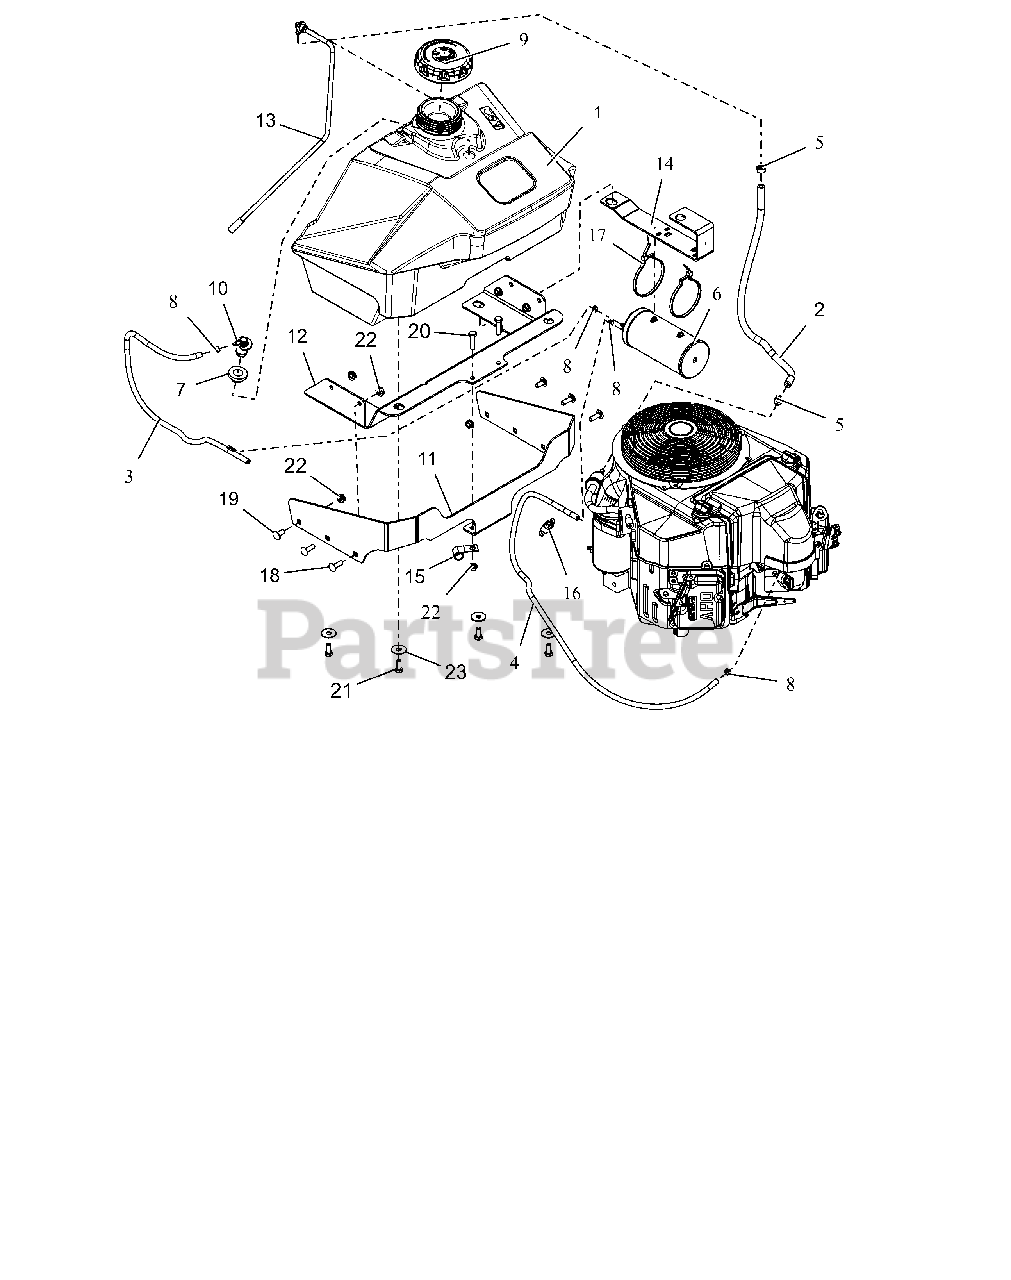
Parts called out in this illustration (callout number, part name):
1	TANK, PRO-WALK
2	HOSE, .25 LOW-PERM BULK GAS
3	HOSE, .188 LOW-PERM BULK GAS
4	HOSE, .188 LOW-PERM BULK GAS
5	CLAMP, FUEL LINE
6	400 CC CARBON CANISTER 3/16 PT
7	GROMMET, REMOTE VENT NITRILE
8	CLAMP-HOSE, SPRING .188
9	CAP, FUEL NONVENT AUTOLOCK
10	VALVE, 2-WAY
11	BRKT, FUEL TANK MTG (RED)
12	BRKT, FUEL
13	ASM, PROWALK FUEL TANK PICK UP
14	BRKT, CARBON CANISTER MTG (RED)
16	CLIP, T, .38-.50
17	CABLE TIE, .19 X 14.4
18	@BLT-RHDSSQNK .31-18X1.00 G5YZ
19	@BLT-RHDSSQNK .31-18X.75 G5YZ
20	@BLT-HEX .31-18X1.25 GR5 YWZC
21	@BLT-HEX .31-18X.75 GR5 YWZC
22	@NUT-LK-CTR-FLG .31-18 YZ GR F
23	WSHR-FL-STL .375X1.125X.065YWZ
